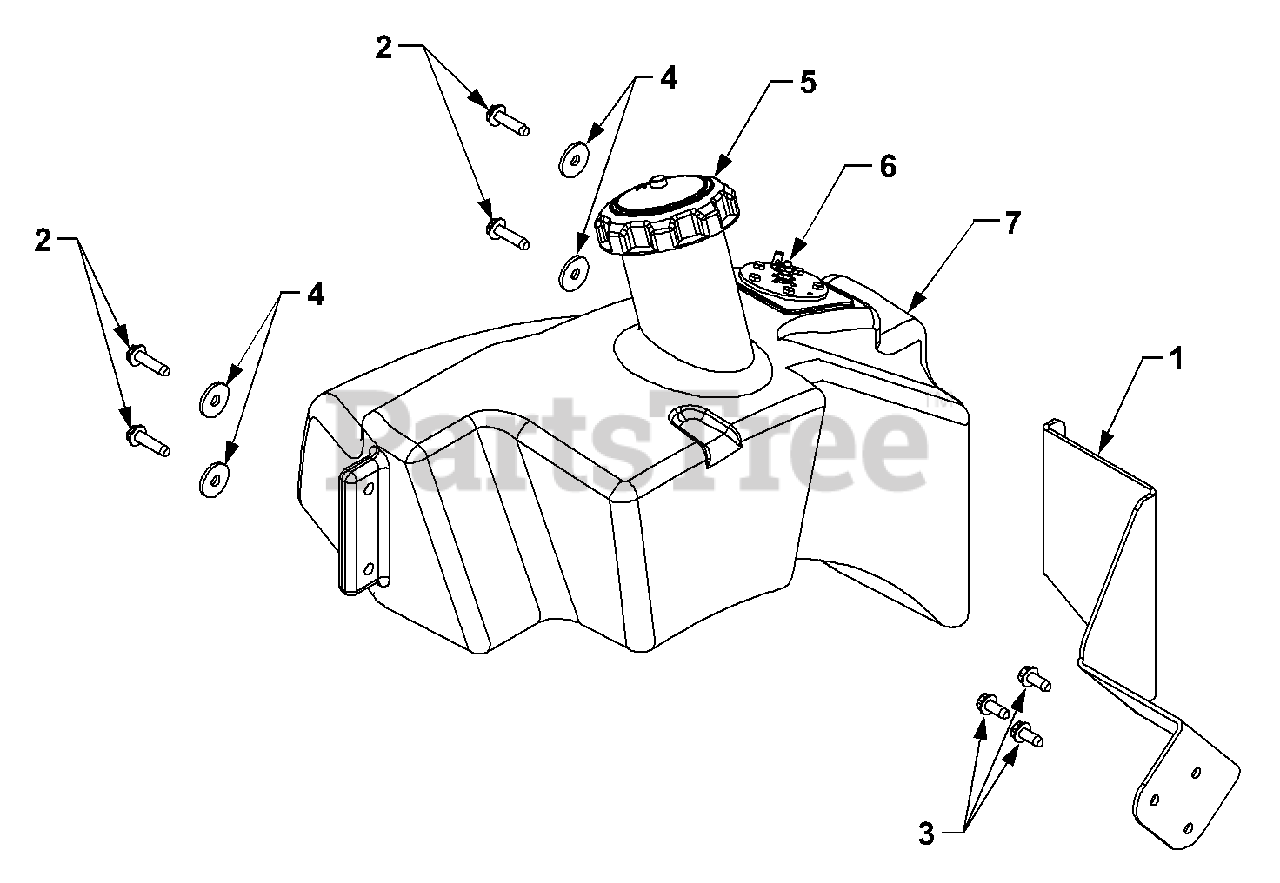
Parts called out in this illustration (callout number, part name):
1	Bracket, Front Tank Mtg.
2	Screw, Hex Wash Hd Tapp 5/16-18 x 1.25
3	Screw, Hex Wash Hd Tapp 5/16-18 x .75
4	Washer, Flat, .344 x 1.125 x .12
5	Cap, Fuel
6	Sensor, Fuel Level
7	Tank, Fuel
